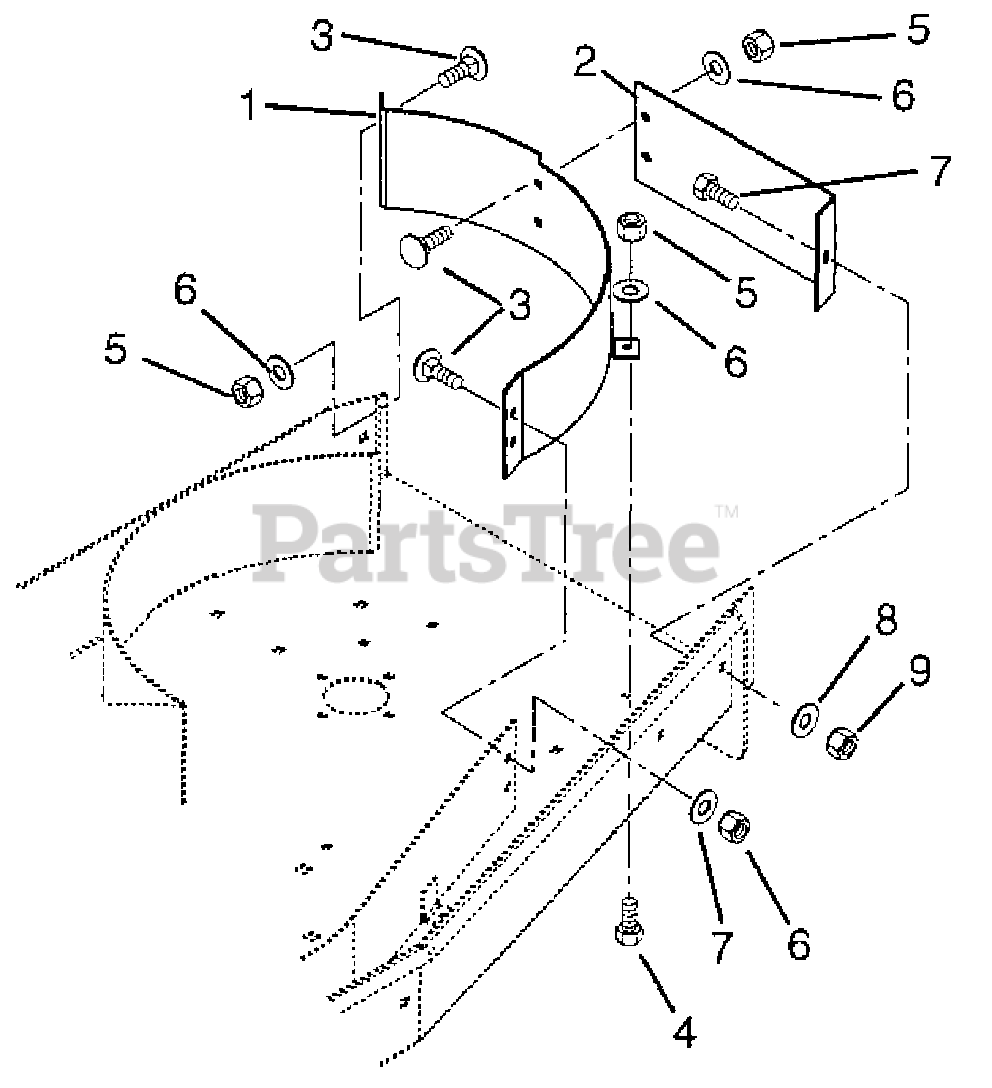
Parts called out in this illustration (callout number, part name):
1	Baffle, Weldment End (50")
1	Baffle, Weldment End (60")
1	Baffle, Weldment End (72")
2	Baffle, Mulching Support (50")
2	Baffle, Mulching Support (60")
2	Baffle, Mulching Support (72")
3	Bolt, Round Head Square Shank .31-18 x .75
4	Bolt, Hex .31-18 x 1.00 Grade 5
5	Nut, Locking Nylon .31-18
6	Washer, Flat Steel .344 x .688 x .065
7	Bolt, Hex .38-16 x 1.00 Grade 5
8	Washer, Flat Steel .38 x .875 x .083
9	Nut, Locking Nylon .38-16
